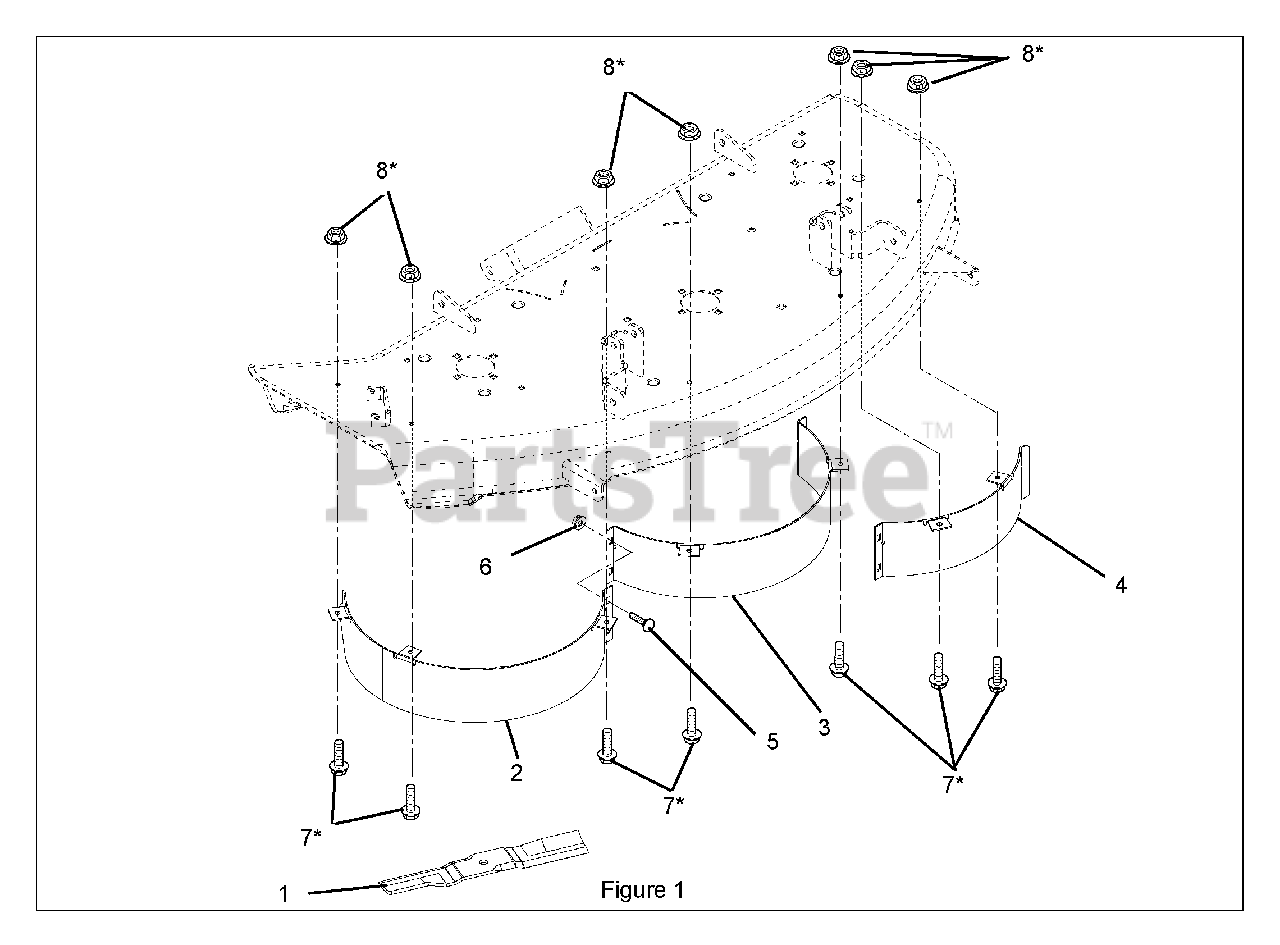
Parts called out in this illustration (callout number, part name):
1	BLD,MULCHING 50" MWR
2	MULCH BAFFLE, CHUTE
3	MULCH BAFFLE,CENTER
4	MULCH BAFFLE, LEFT
5	@BLT-RDHDSQNK .31-18X1.00 G5YZ
6	@NUT-LK-TOP-FLG .31-18 YWZC
7	@BLT-HEX .31-18X.75 GR5 YWZC
8	@NUT-SPNLK-FLG .312-18 YWZC
